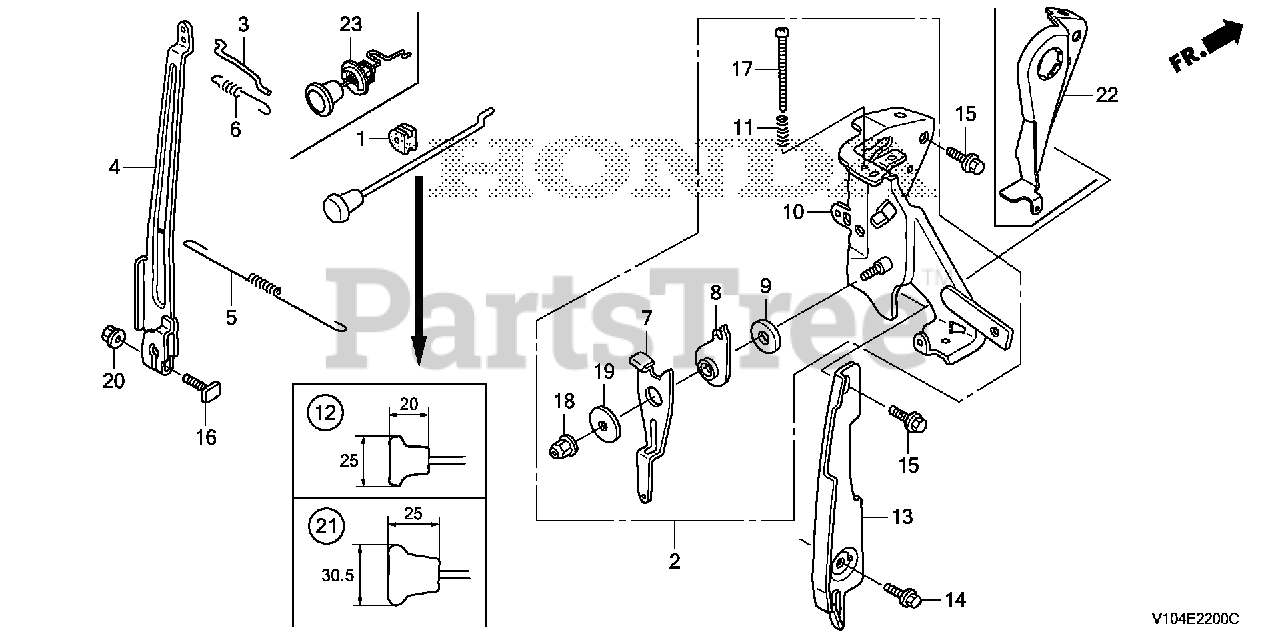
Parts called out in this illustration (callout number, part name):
3	ROD, GOVERNOR
4	ARM, GOVERNOR
5	SPRING, GOVERNOR
6	SPRING, THROTTLE RETURN
13	PLATE, SIDE
14	BOLT, FLANGE (6X12) (CT200)
15	BOLT, FLANGE (6X14) (CT200)
16	BOLT, GOVERNOR ARM
20	NUT, FLANGE (6MM)
22	BASE, CONTROL
23	ROD, CHOKE CONTROL
